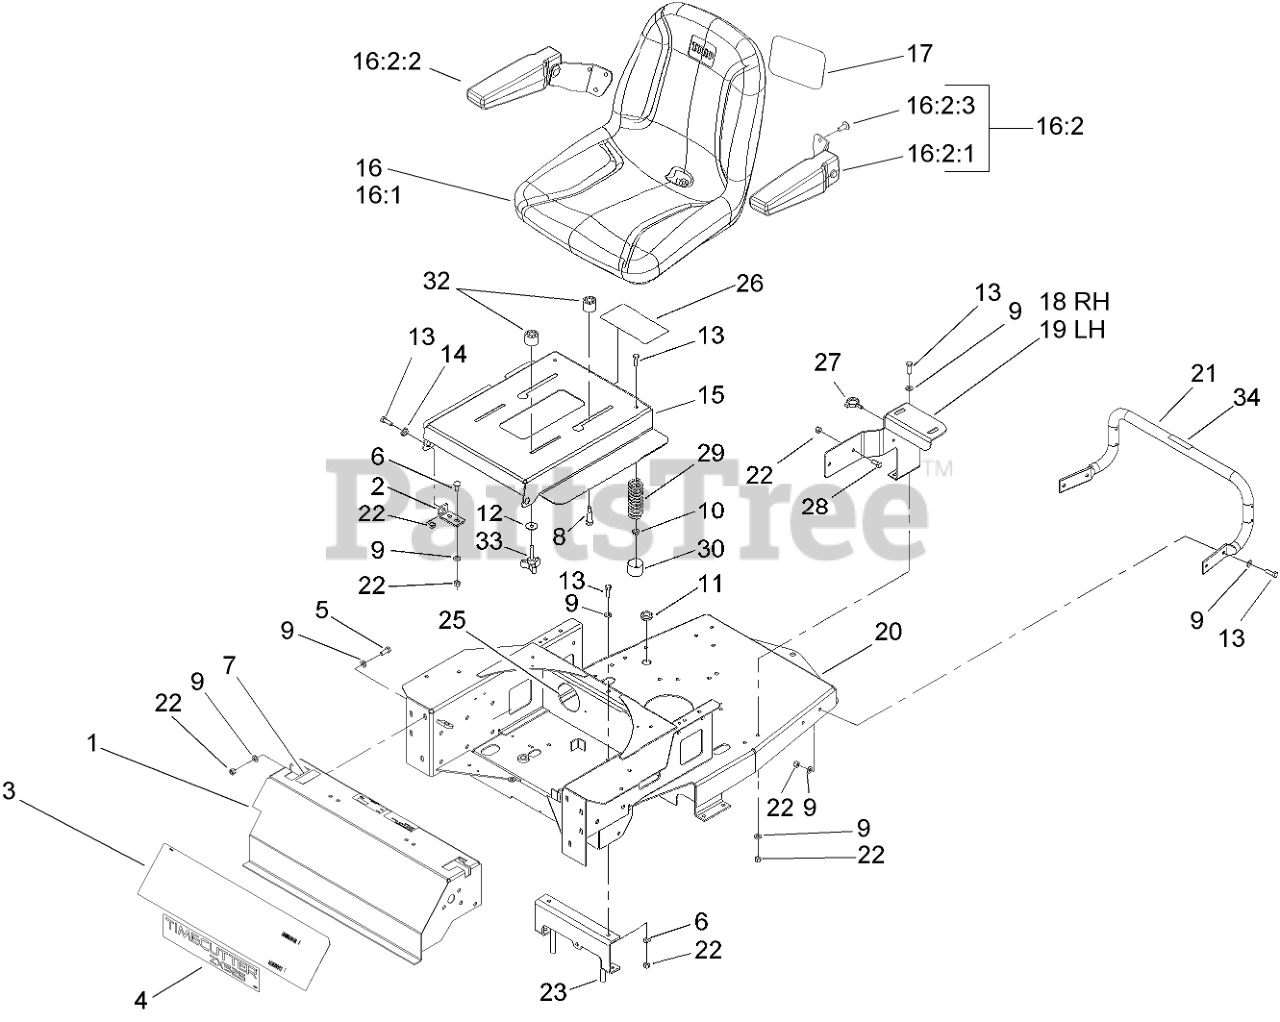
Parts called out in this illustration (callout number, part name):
2	BRACKET-PIVOT
3	DECAL-DANGER
5	SCREW-HH
6	SCREW-CARR
7	DECAL-CONTROL, MOTION
8	SCREW-SHOULDER, HH
9	WASHER-PLAIN
10	NUT-HF
11	GROMMET
12	WASHER-PIVOT
13	SCREW-HH
14	BUSHING
15	SEAT PAN ASM
16	SEAT (WITH ARM RESTS)
16:1	SEAT
16:2	ARMREST KIT
16:2:1	LH ARMREST ASM
16:2:2	RH ARMREST ASM
16:2:3	SCREW-HSBH
17	DECAL
18	BRACKET-RH
19	BRACKET-LH
20	REAR FRAME ASM
21	ROD-SUPPORT, REAR
22	NUT-LOCK, NI
25	COVER-CONDUIT
26	DECAL-SERVICE
27	CLAMP-HOSE
28	SCREW-HH
29	SPRING-COMPRESSION
30	CAP-PROTECTOR
32	SPACER
34	DECAL-WARNING
